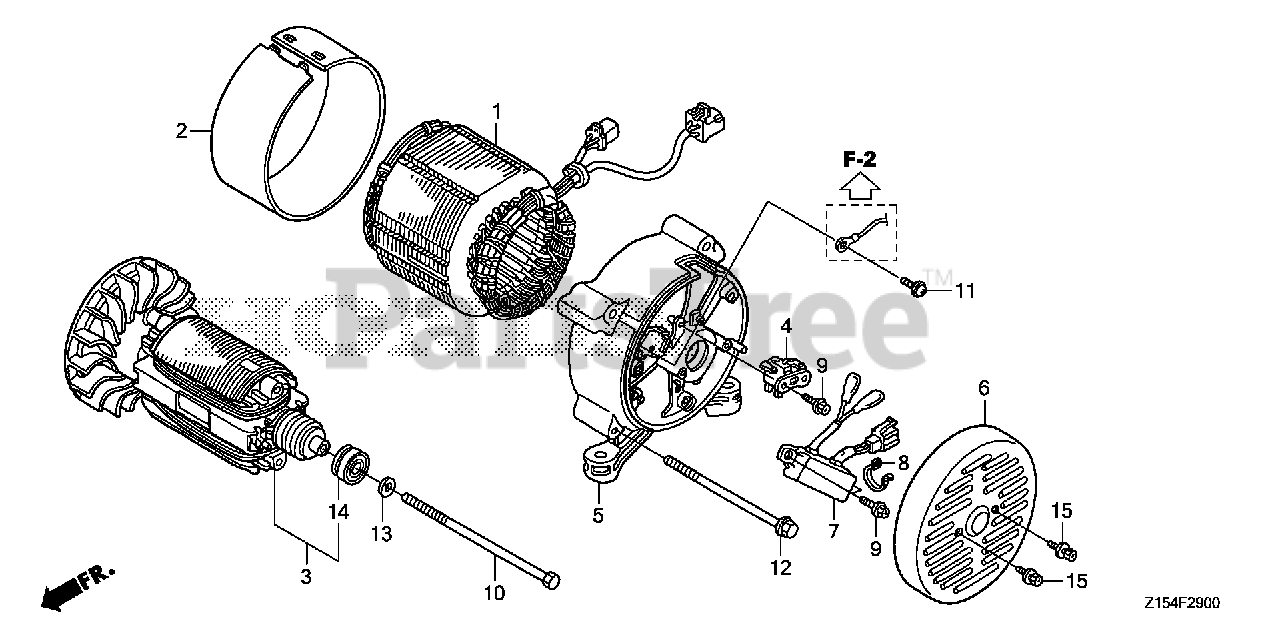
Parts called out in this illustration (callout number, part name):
1	STATOR ASSY.
2	COVER, STATOR *NH1* (BLACK)
4	BRUSH ASSY.
5	HOUSING, RR.
6	COVER, GENERATOR END *NH1* (BLACK)
7	REGULATOR ASSY., AUTOMATIC VOLTAGE
8	TIE, CABLE (C)
9	SCREW, TAPPING (5X14)
10	BOLT, HEX. (5/16X180)
11	SCREW, PAN (5X12)
12	BOLT, FLANGE (6X125)
13	WASHER, PLAIN (8MM)
14	BEARING ASSY. (6202NCX)
15	BOLT-WASHER (5X10)
